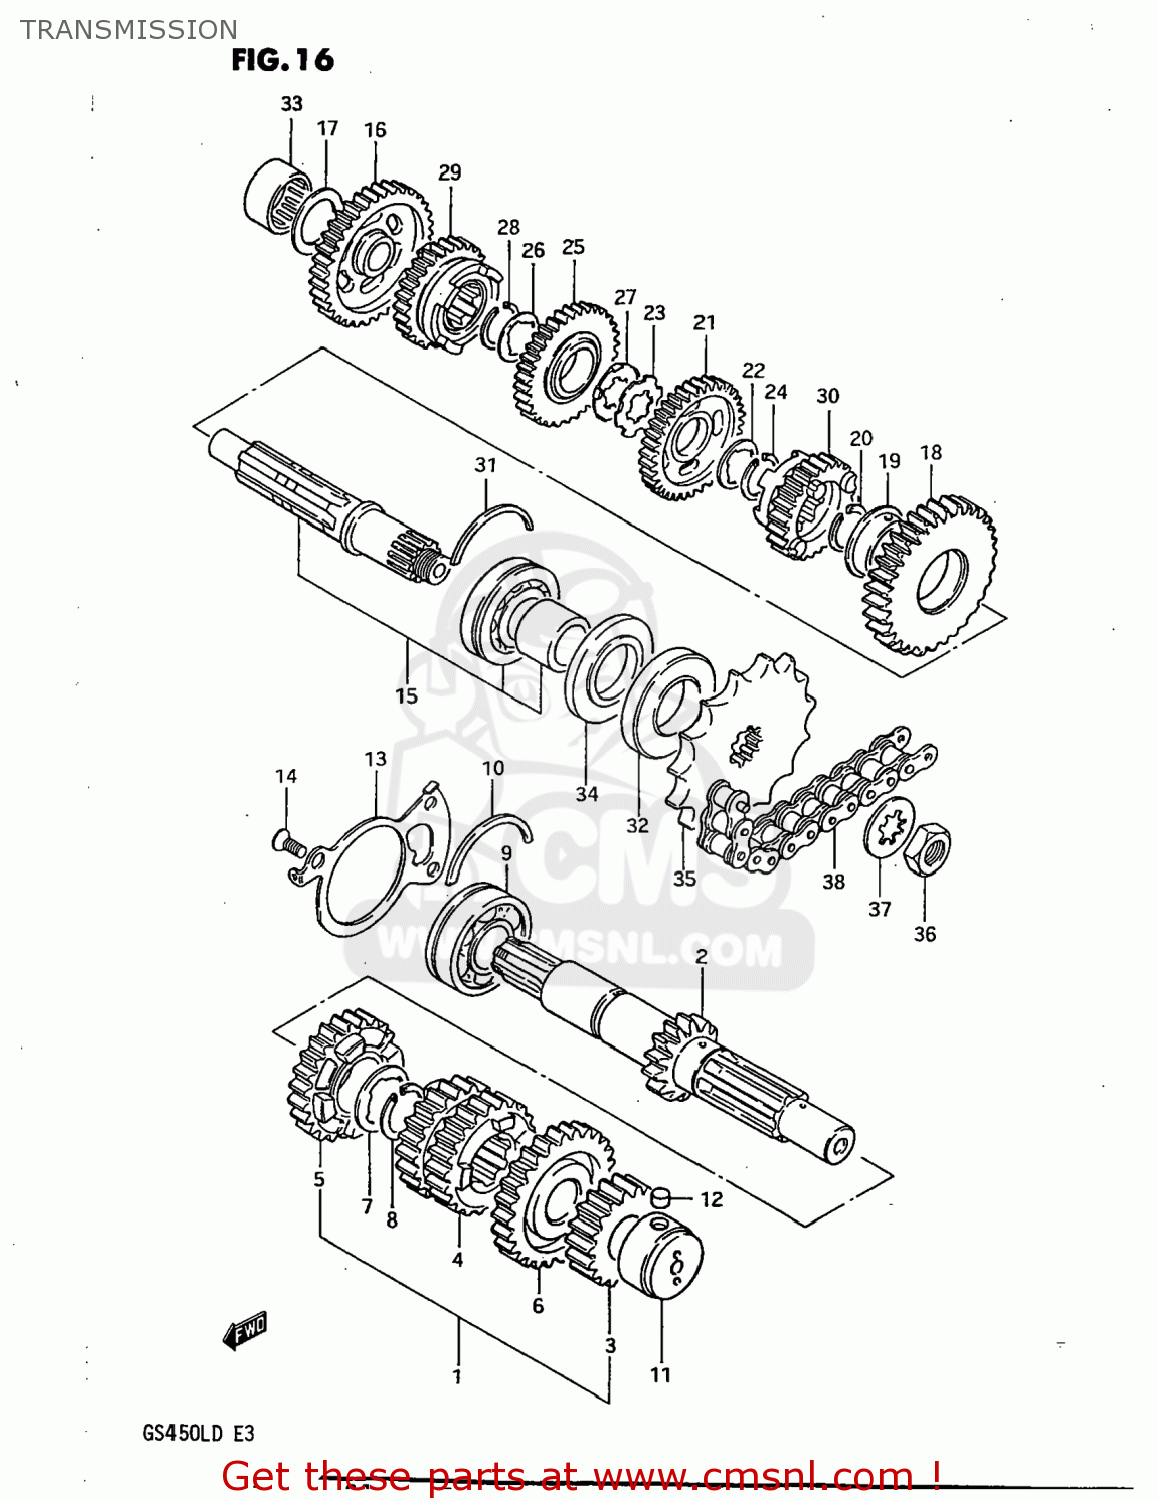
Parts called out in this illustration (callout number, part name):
1	SHAFT,COUNTER
2	SHAFT,COUNTER
3	GEAR,2ND DRIVE(NT:18)
4	GEAR,THIRD DRIVE
5	GEAR,FIFTH DRIVE
6	GEAR,SIXTH DRIVE
7	WASHER
8	CIRCLIP
9	BEARING(25X62X17)
10	C-RING
11	ROLLER BEARING (20X34X2
12	PIN
13	PLATE,COUNTERSHAFT BEARING
14	SCREW
15	SHAFT,DRIVE
16	GEAR,FIRST DRIVEN
17	WASHER
18	GEAR,SECOND DRIVEN
19	BUSHING
20	CIRCLIP
21	GEAR,THIRD DRIVEN
22	WASHER,LOCK
23	WASHER,LOCK
24	CIRCLIP
25	GEAR,FOURTH DRIVEN
26	WASHER,LOCK
27	WASHER
28	CIRCLIP
29	GEAR,5TH DRIVEN(NT:25)
30	GEAR,SIXTH DRIVEN
31	C-RING
32	SEAL,OIL(32X62X7)
33	ROLLER BEARING (20X34X1
34	SEAL,OIL(32X62X5.5)
35	SPROCKET,ENGINE(NT:16)
36	NUT
37	WASHER
38	CHAIN,DRIVE #50UB-108
